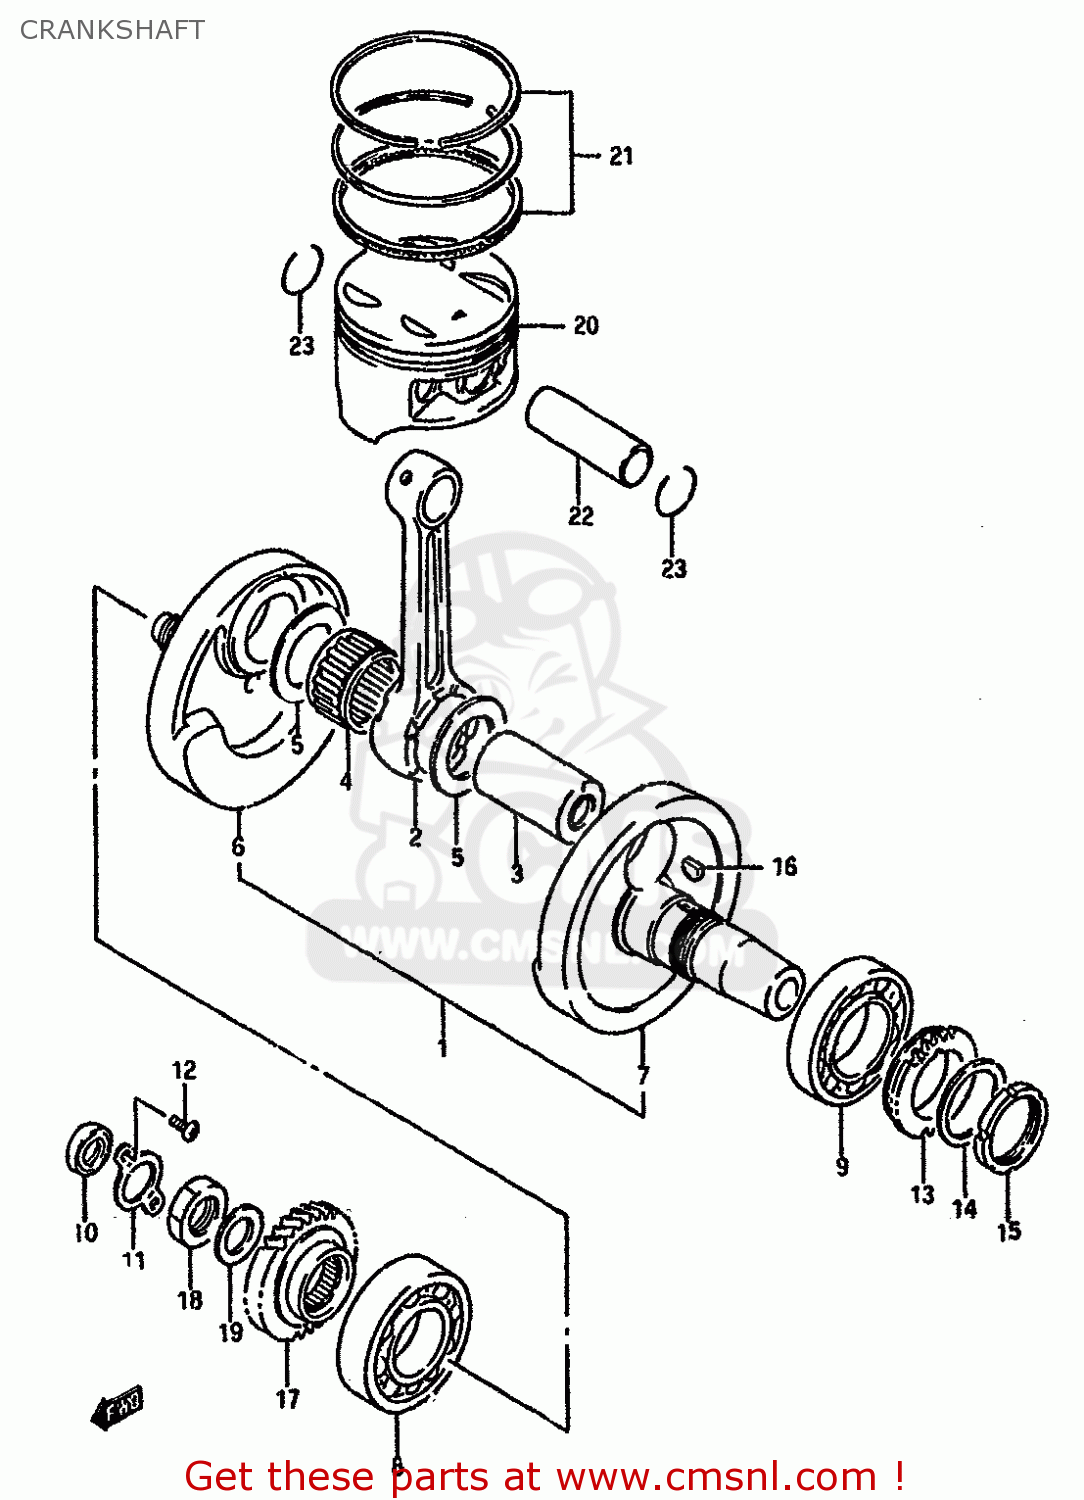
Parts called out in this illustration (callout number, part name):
1	CRANKSHAFT ASSY
2	ROD,CONNECTING
3	PIN,CRANK
4	BEARING(41X51X25)
5	WASHER
6	CRANKSHAFT,RH
7	CRANKSHAFT,LH
8	BEARING(40X90X23)
9	BEARING(45X85X19)
10	SEAL,OIL(16X30X6)
11	RETAINER,CRANKSHAFT BEARING,R
12	SCREW
13	SPROCKET,BAL.D
14	WASHER
15	NUT,BAL DRIVE SPRKT
16	KEY
17	GEAR,PRIMARY DRIVE (NT:32)
18	NUT
19	WASHER
20	PISTON 105MM
21	RING SET,PISTON
22	PIN,PISTON
23	CIRCLIP
